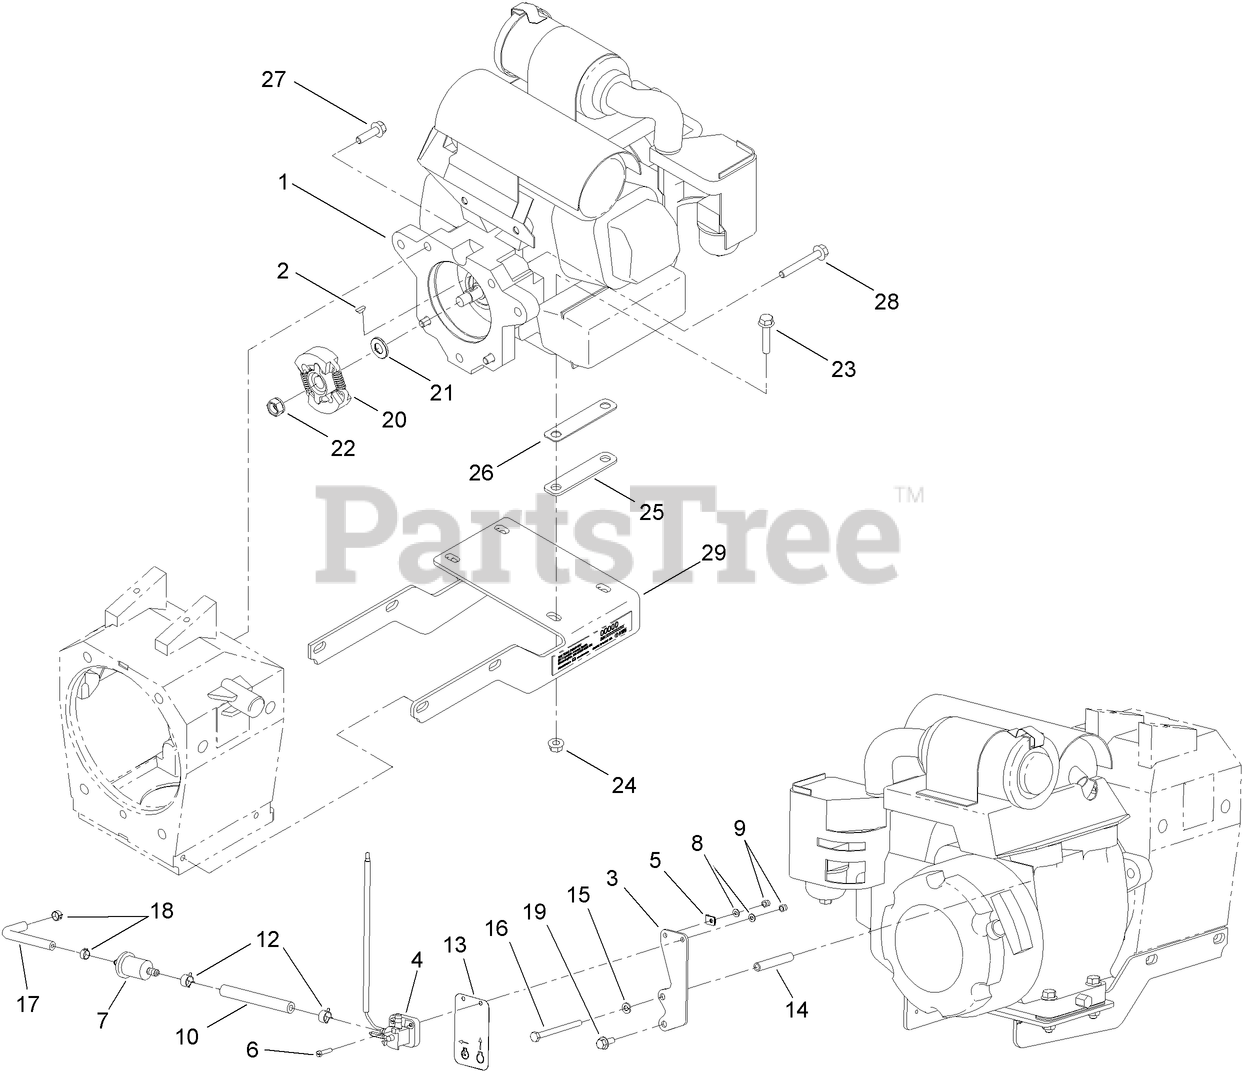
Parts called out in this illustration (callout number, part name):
1	ENGINE-HONDA, GX120
2	KEY-WOODRUFF
3	PLATE-SWITCH, STOP
4	FUEL SHUT OFF VALVE ASM
5	CLAMP
6	SCREW-HH
7	FILTER-FUEL
8	WASHER-FLAT
9	NUT-LOCK
10	HOSE-FUEL
12	CLAMP-HOSE, FUEL
13	HANG TAG-RUN, STOP
14	TUBE-SWITCH, STOP
15	WASHER-LOCK, SPRING
16	SCREW-HH
17	HOSE-FUEL
18	CLAMP-HOSE, FUEL
19	SCREW-HHF
20	CLUTCH-FRICTION
21	SPACER-CLUTCH
22	NUT-HEX FLANGE
23	SCREW-HHF
24	NUT-HF
25	SHIM-ENGINE (11GA)
26	SHIM-ENGINE (16GA)
27	SCREW-HHF
28	SCREW-HHF
29	SUPPORT-ENGINE
